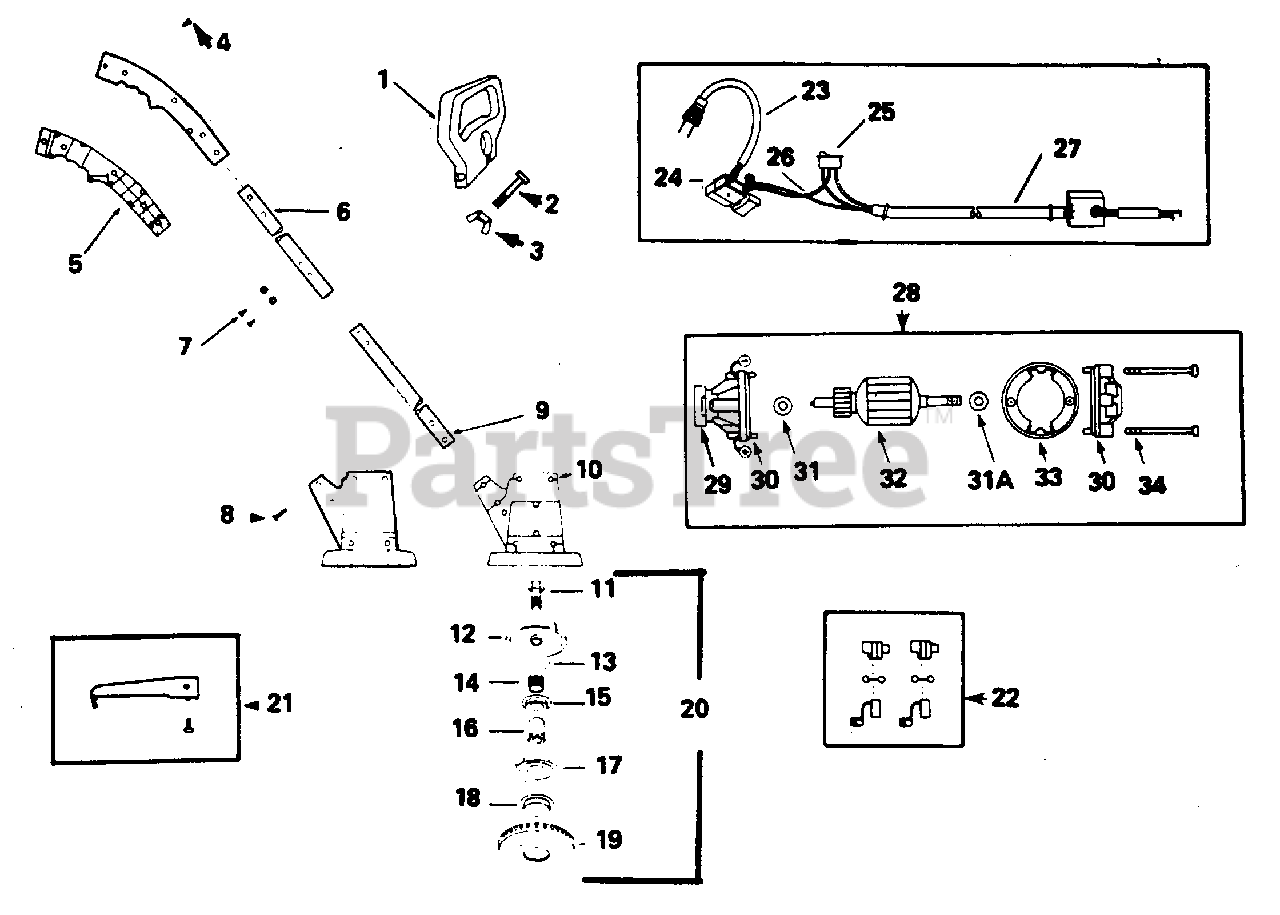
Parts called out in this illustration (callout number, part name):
1	ASSIST HANDLE
3	WING NUT
5	TRIGGER HANDLE SET
6	TUBE, UPPER
7	TUBE FASTENER KIT
9	TUBE, LOWER
10	MOTOR HOUSING SET
11	DRIVE ADAPTOR
12	HUB w/LINE SAVER
13	LINE SAVER
14	COIL SPRING
15	COIL SPRING ADAPTOR
16	DRIVE GEAR
17	SPOOL, w/LINE
18	RELEASE BUTTON
20	TAP-N-GO HEAD ASSEMBLY
21	LINE LIMITER KIT
22	BRUSH KIT
23	POWER SUPPLY CORD
25	SWITCH, TOGGLE (For 92705 Harness)
25	SWITCH, TOGGLE (For 92706 Harness)
26	WIRE, JUMPER
27	HARNESS w/RECTIFIER & TOGGLE SWITCH
29	INSULATOR
30	END BELL SET
31	WASHER, THRUST .025"
31A	WASHER, THRUST .010"
32	ARMATURE
33	FIELD ASSEMBLY
